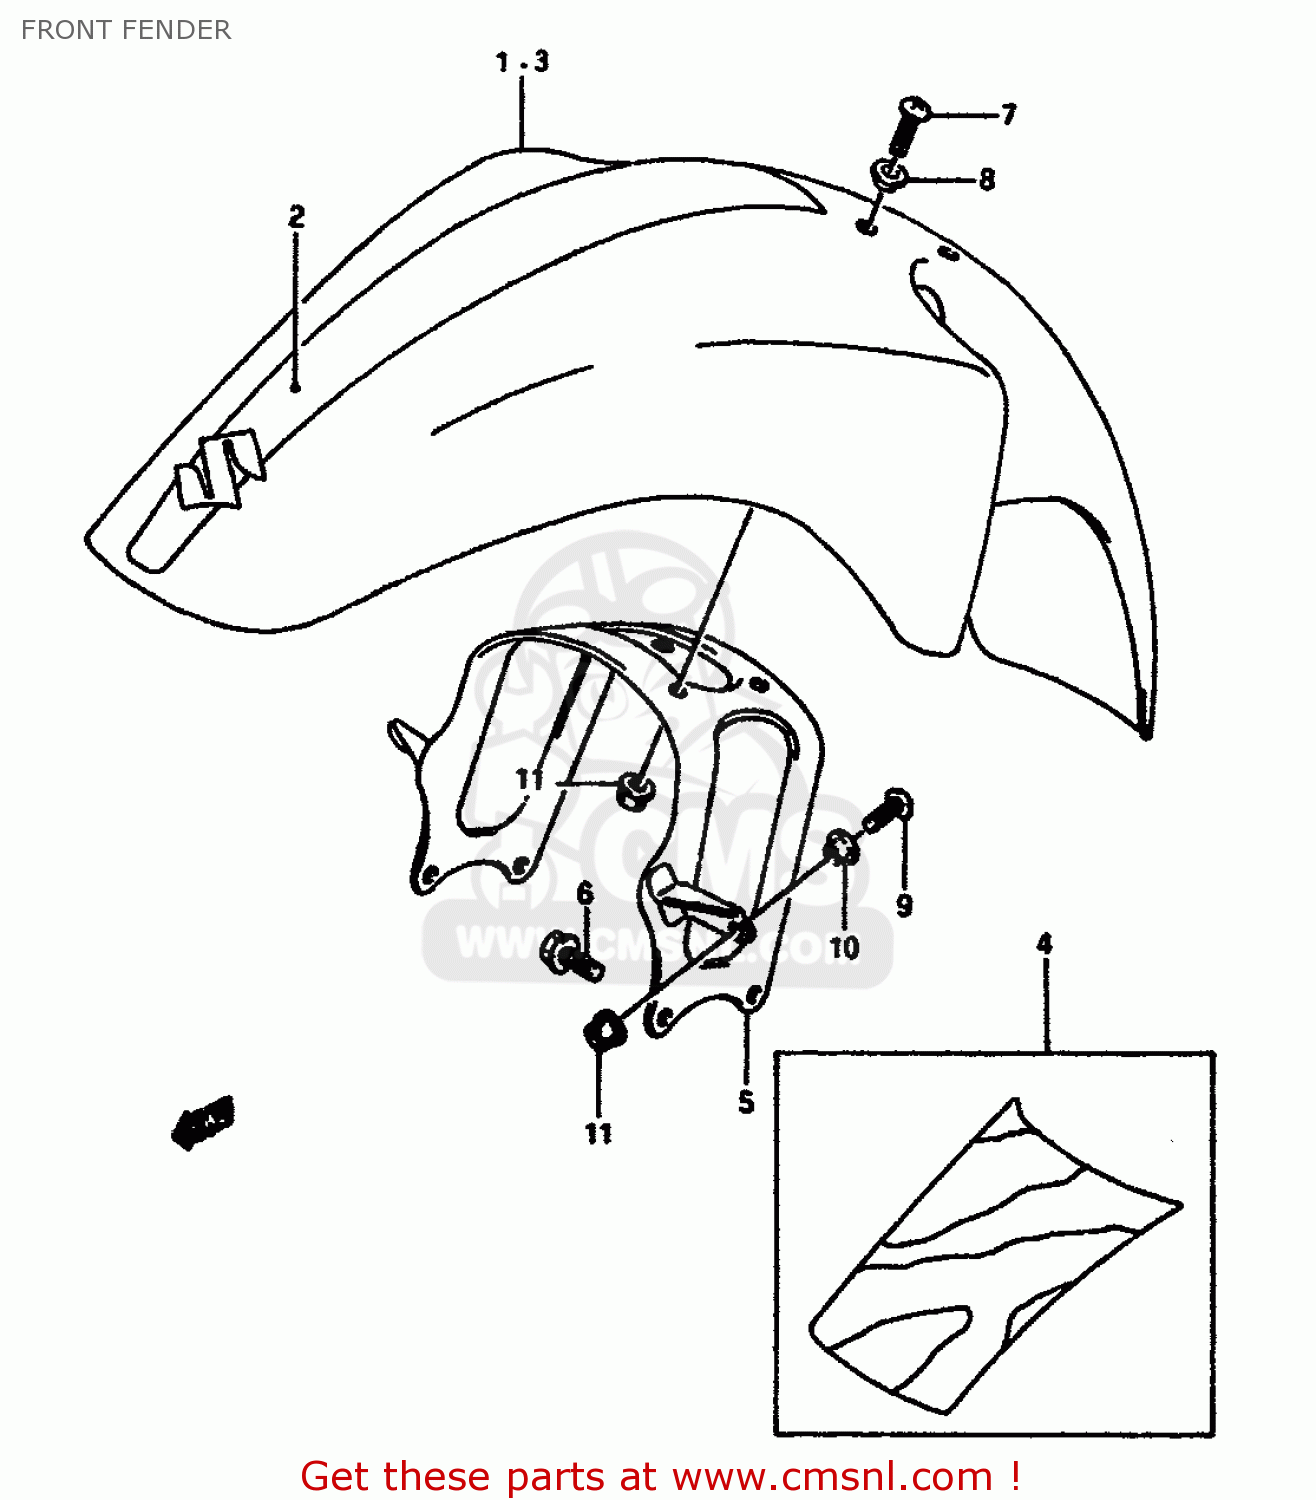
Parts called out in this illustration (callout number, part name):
1	FENDER,FRONT
2	TAPE
3	FENDER,FRONT
4	TAPE
5	BRACE,FR FENDER
6	BOLT 6X16
7	SCREW
8	WASHER
9	SCREW
10	WASHER
11	NUT
